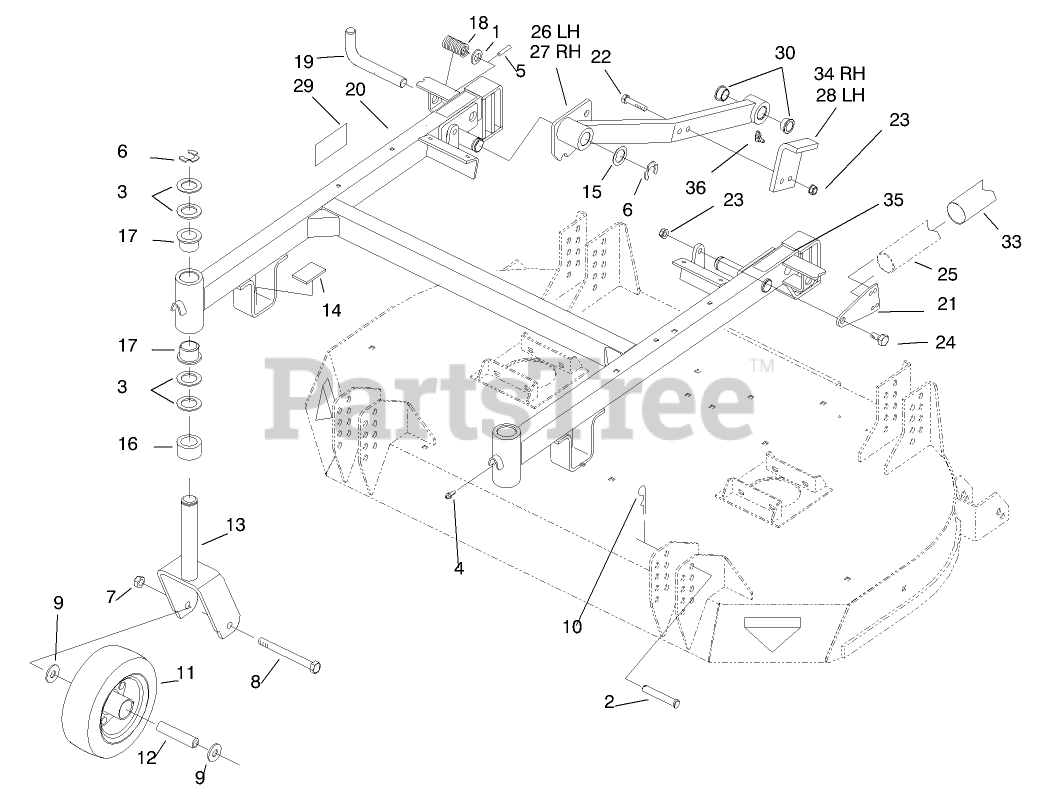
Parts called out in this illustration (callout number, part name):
1	WASHER
2	PIN-CLEVIS
3	WASHER-THRUST
4	FITTING-GREASE
5	PIN-ROLL
6	RING-RETAINING
7	NUT-HEX
8	SCREW-HH
9	WASHER-FLAT
10	PIN-HAIR
11	CASTOR WHEEL ASM
12	SPANNER-TIRE
13	Castor Fork
14	CUSHION - RUBBER
15	Washer
16	SPACER-CASTOR
17	BUSHING
18	SPRING-COMPRESSION
19	PIN - PIVOT
20	Frame-Carrier
21	PLATE-END, SPRING
22	SCREW-HH
23	NUT-LOCK, NI
24	BOLT-SHOULDER
25	SPRING-EXTENSION
26	LH Push Arm ASM
27	RH Push Arm ASM
28	Stop-Pusharm
29	DECAL - HOC
30	BEARING-FLANGE
33	COVER-SPRING
34	STOP - PUSH ARM,RH R
35	DECAL-WARNING
36	FITTING-GREASE
